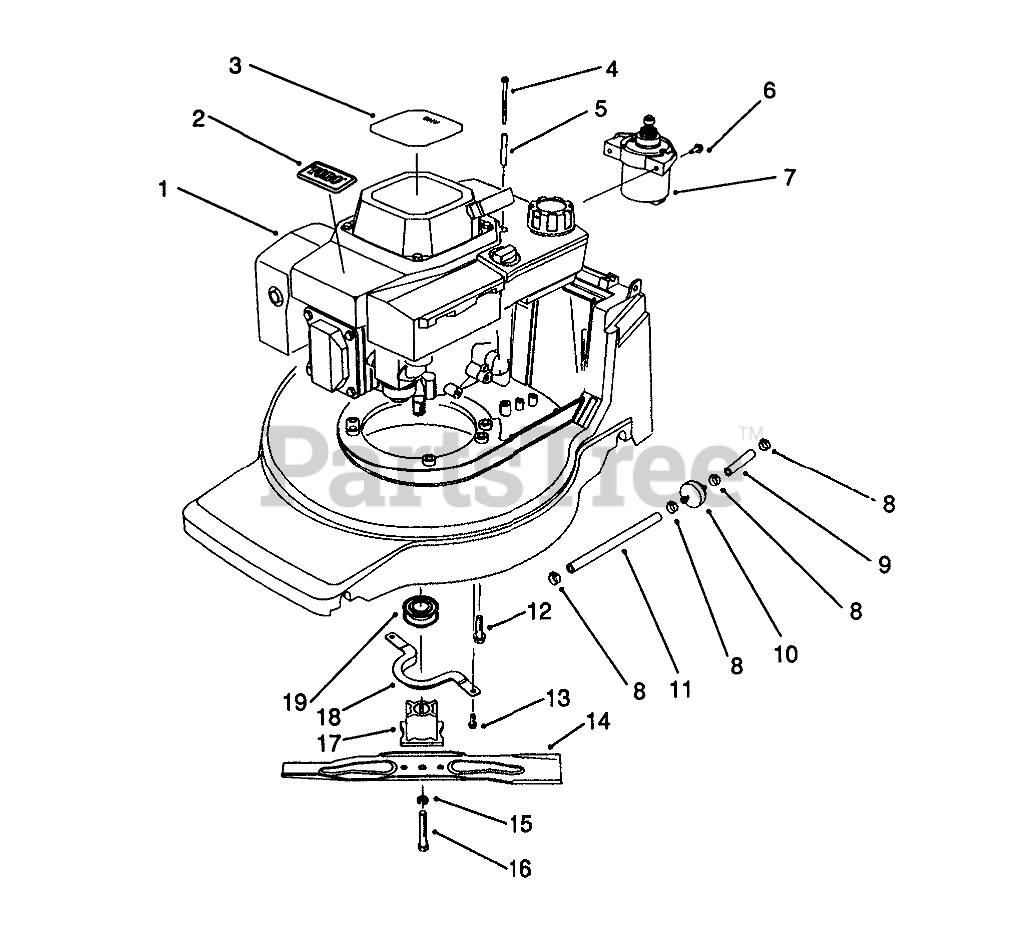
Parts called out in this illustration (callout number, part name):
1	ENGINE ASSY OHV BBC/K
2	TORO LOGO PLT
3	DECAL-HV INT'L
4	THRD FORMING SCREW
5	TUBULAR SPACER
6	SCREW
7	STARTER MOTOR ASM
8	CLAMP-FUEL LINE
9	LINE-GAS
10	FILTER-FUEL
11	HOSE-FUEL
12	SCREW-HWHTF
13	SCREW-HWH
14	Blade-48cm
15	WASHER-LOCK
16	BOLT-BLADE
17	BLADE RETAINER - 25 MM
18	Guide-Belt
19	PULLEY-DRIVE, ZONE START
